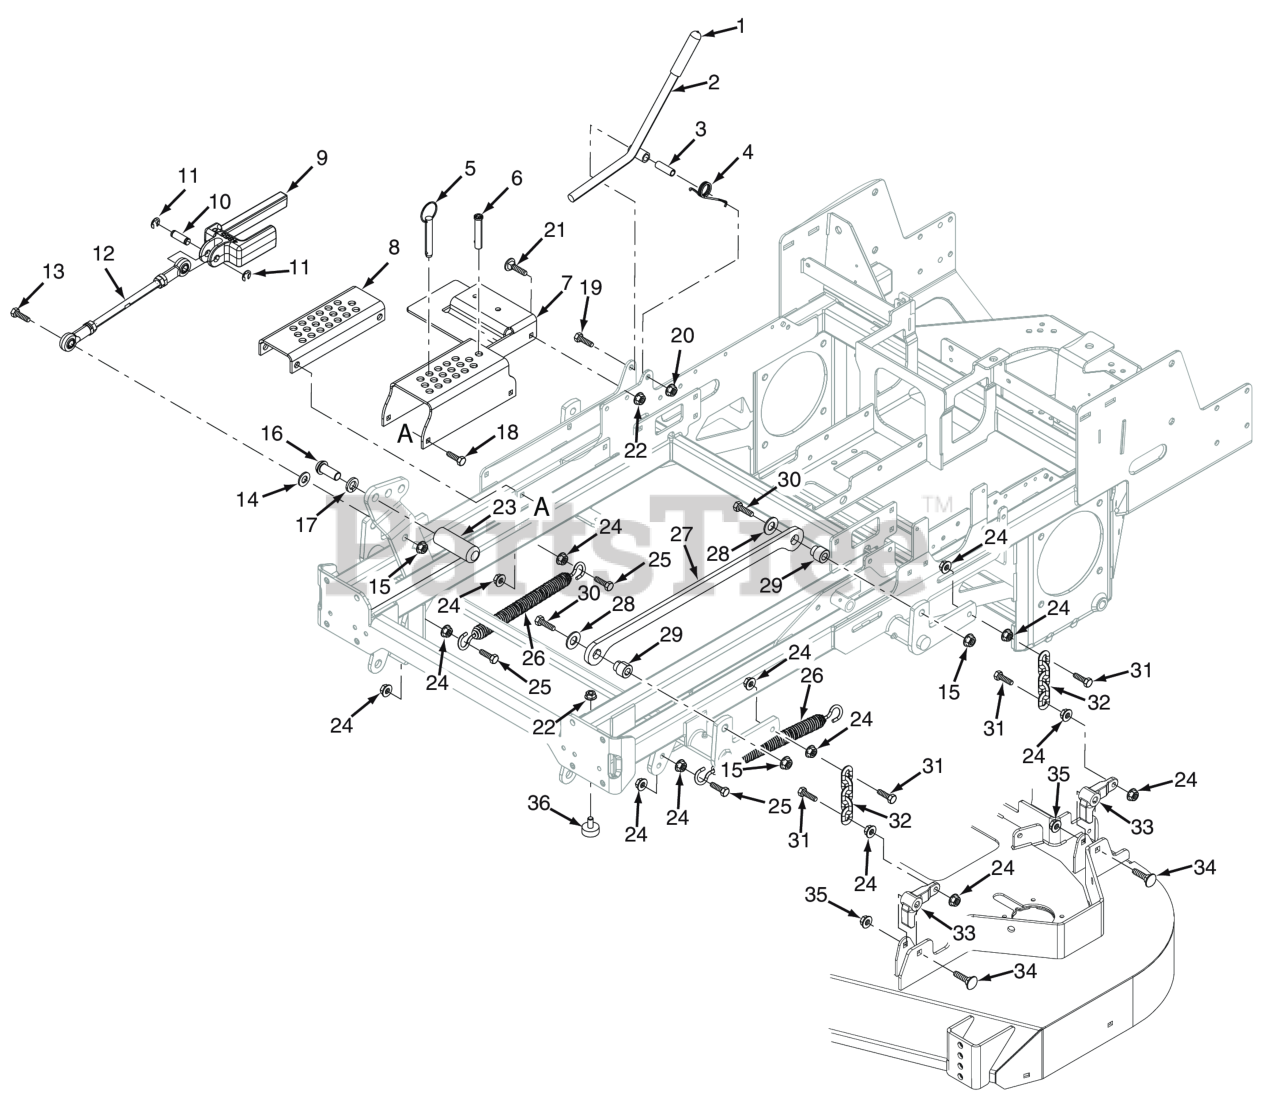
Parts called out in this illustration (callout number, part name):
1	Mounting Bracket, Fuel Tank
2	Deck Latch Assembly w/Grip
3	Bushing, .502 O.D.
4	Spring, Torsion - Lever Return
5	Lanyard, Deck Height Pin Assembly
6	Pin, Locking
7	Adjustment Bracket, Upper Cut Height
8	Adjustment Bracket, Lower Cut Height
9	Slide, Height Adjustment Assembly (INCL. 10,11,12)
10	Pin, Deck Lift
11	Retaining Ring, 1/2" Ext. "E"
12	Linkage, Deck Lift
12	Rod End, 1/2-20 Female RH Thread
12	Rod End, 1/2-20 Female LH Thread
12	Nut, 1/2-20 UNF-2B RH Thread
12	Bolt, Hex Hd. 5/16-18 x 3-3/4"
13	Hex Head Bolt, 1/2-13 x 2"
14	Flatwasher, 1/2 - .531 x 1.062 x .095
15	HEX LOCKNUT, ELASTIC STOP, 1/2-13
16	Capscrew, 5/8-11 x 1-1/2"
17	Lockwasher, 5/8" Spring
18	Bolt, Hex Wshr Head 5/16-18 x 1-1/4"
19	Capscrew, Hex Head 3/8-16 x 2.75"
20	HEX NUT, ELASTIC STOP LOCK, 3/8-16
21	Bolt, 5/16-18 x .75 RHSN Carriage
22	Nut, Serrated Flange 5/16-18 (Right Front Engine Mounting, Briggs and Kohler Only)
23	Foot Pedal, Height Adjustment
24	NUT, 3/8-16 SERRATED FLANGE HEX HEAD
25	Bolt, Hex Head 3/8-16 x 1-1/2" Grade 8 Black
26	Spring, Helper (61" & 72" Cutter Decks Only)
27	Link, Deck Lift
28	Flat Washer, 1/2 (.562 x 1.375 x .109)
29	Pivot, Deck Link
30	Bolt, Hex Head 1/2-13 x 2-1/4"
31	Bolt, Hex Head, 3/8-16 x 1-1/2"
32	Chain, Deck Lift
33	Lever, Deck Level
34	Bolt, Carriage 7/16-14 x 2-1/4"
35	HEX LOCKNUT, ELASTIC STOP, 7/16-14
36	Bumper, Rubber 5/16-18 x 5/8"
